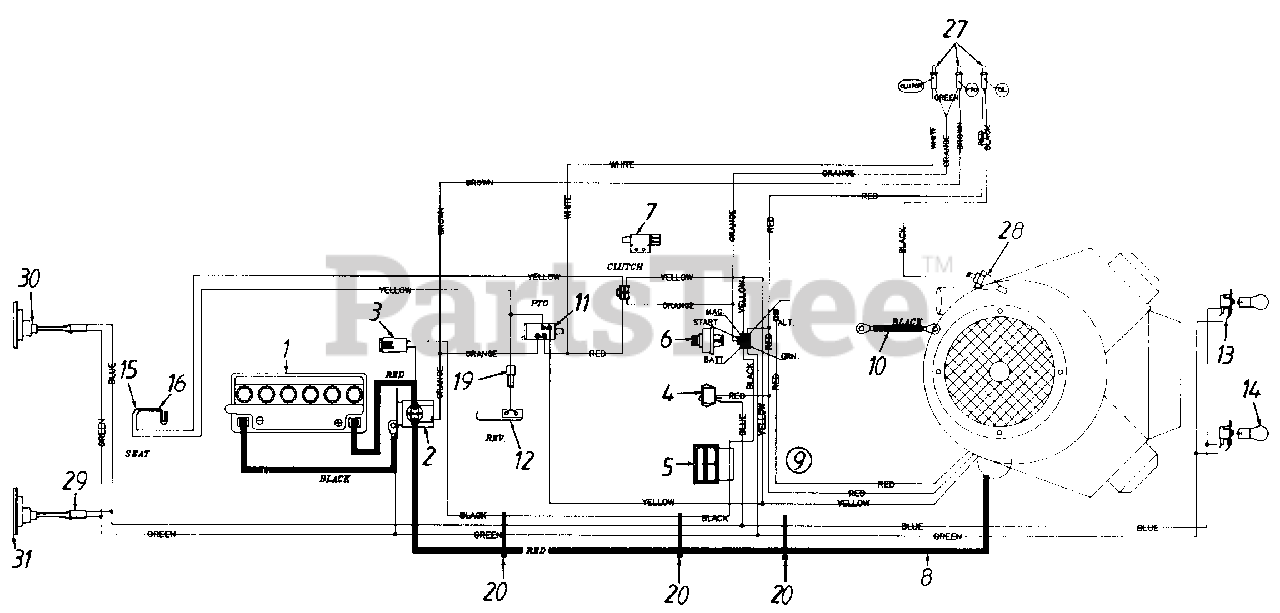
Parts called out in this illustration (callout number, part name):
1	Battery - 12V
2	Solenoid
3	Fuse 20 Amps
4	Light Switch
5	Ammeter
6	Ignition Switch
7	Safety Switch (Clutch)
8	Electric Wire - 30.0" Lg.
9	Wire Harness
10	Ground Wire - 7.5" Lg.
11	Safety Switch (Deck)
12	Safety Switch (Reverse)
13	Headlight Socket (Style 0, 6)
14	Headlight Bulb
15	Safety Switch (Seat)
16	Safety Switch (Seat)
19	Ext. Wire
27	Bulb
28	Oil Pressure Switch
29	Taillight Harness
30	Taillight
31	Taillight Bulb
